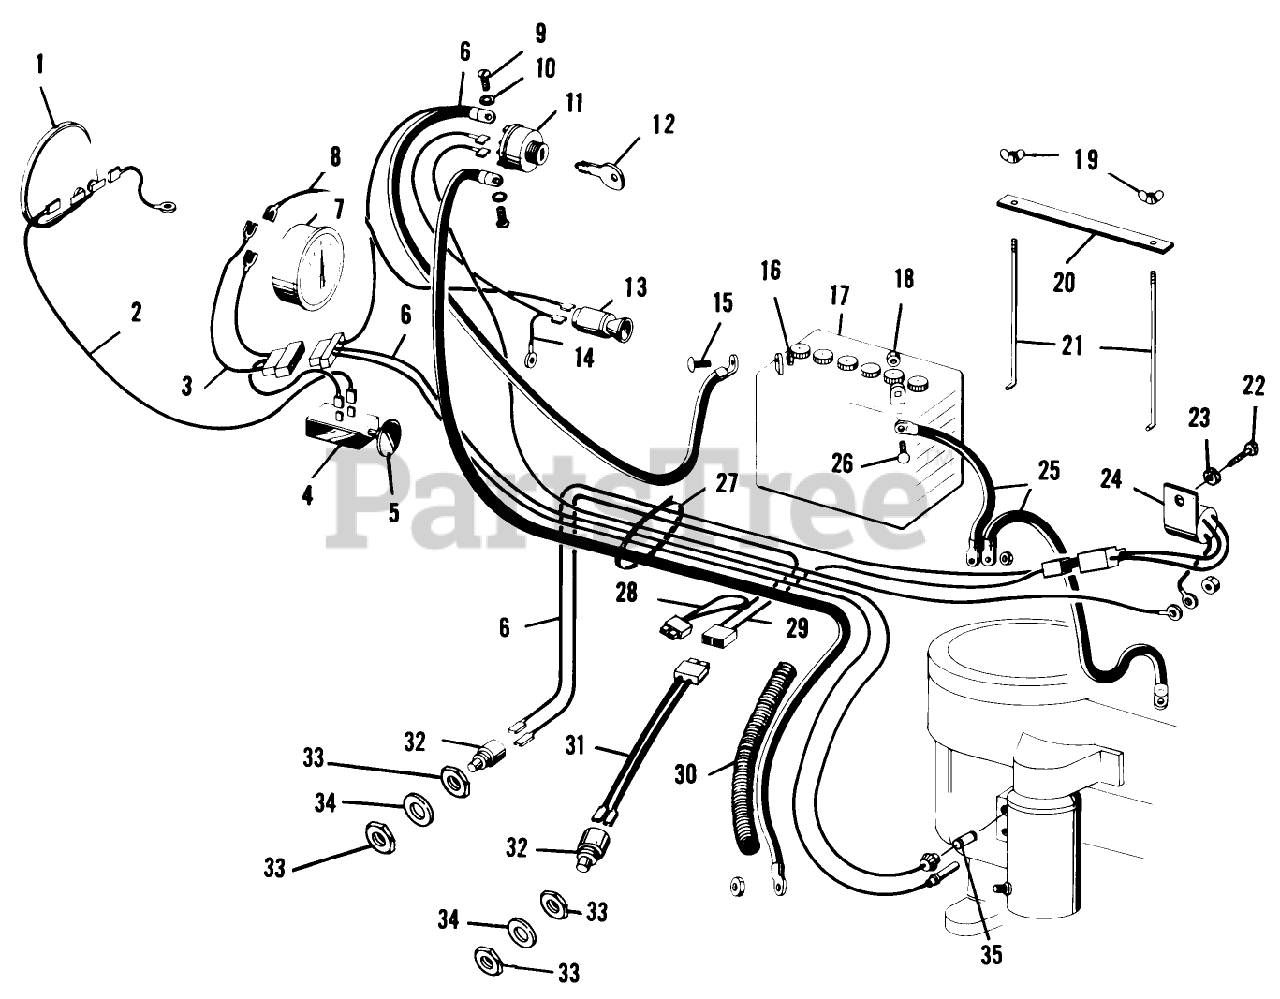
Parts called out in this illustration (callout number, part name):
5	Knob, Light Switch
9	Screw, Rd Hd, No. 10-32 x 3/8 In.
10	Lockwasher #10 External
12	Key, Ignition
15	Bolt 5/16-18 x 5/8 Carriage
16	*Nut, Keps, 5/16-18 Thd
18	*Nut, Hex, 1/4-20 Thd
19	Wingnut
20	Battery Strap
22	Screw-Hex Sems #10-32 x 3/8
23	*Lockwasher, Split, No. 10
26	*Carriage Bolt, 1/4-20 x 3/4 In.
33	Nut (Switch Part)
34	Lockwasher (Switch Part)
